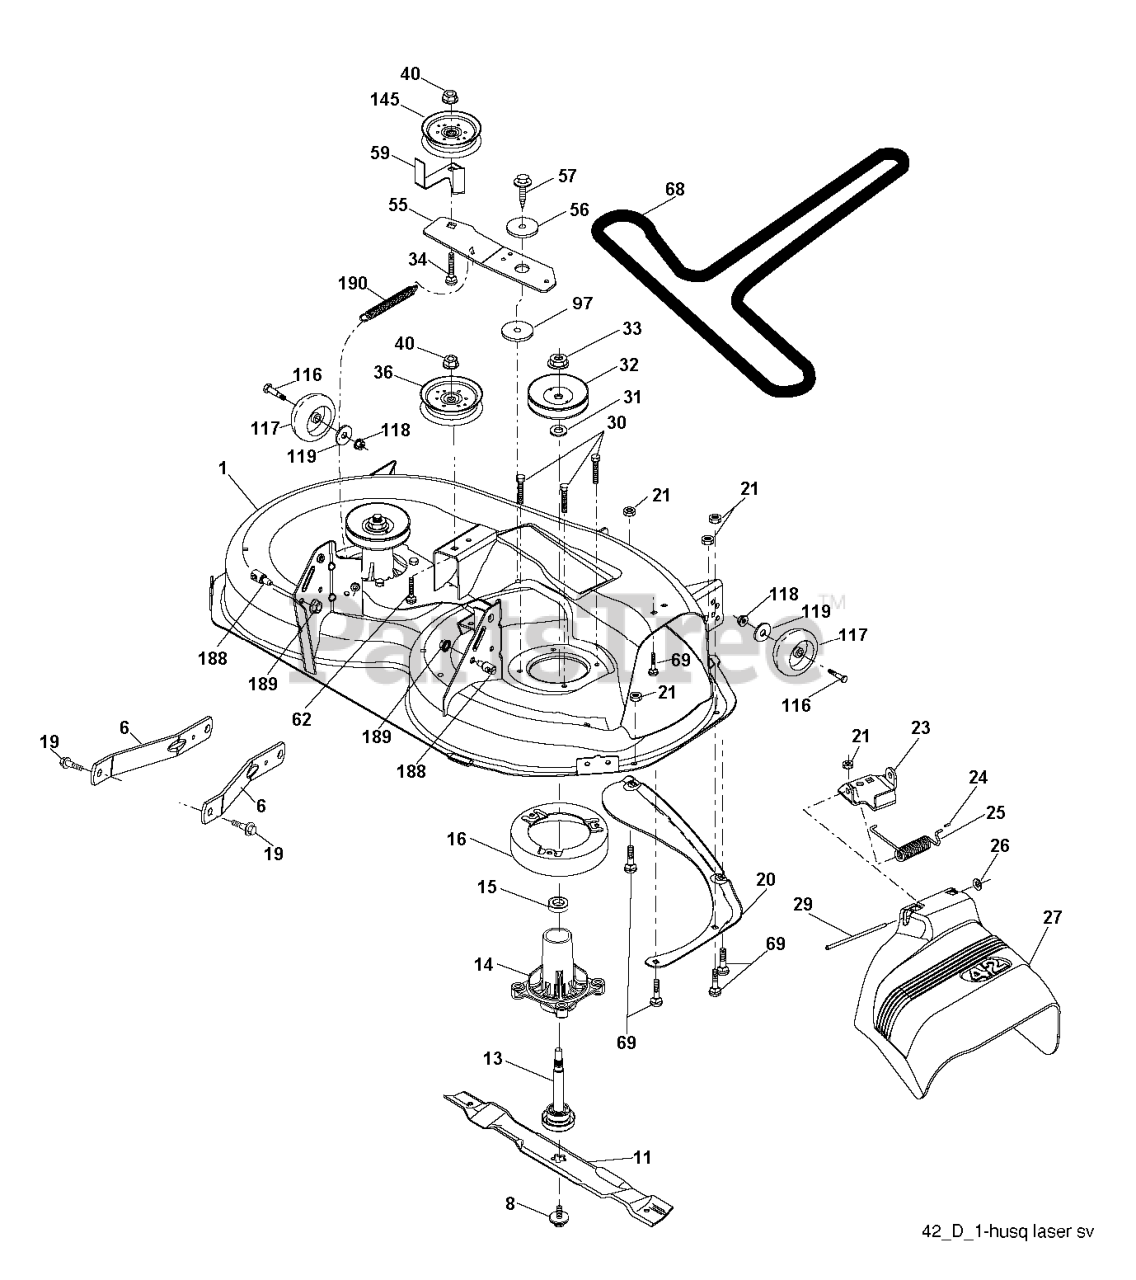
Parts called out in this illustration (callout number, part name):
1	DECK.WELDMENT.42"
6	ARM.SUSPENSION.MOWER.R
8	BOLT.WASHER.ASM.7/16-2
11	42" HI-LIFT BLADE
13	SHAFT.ASM.MDRL.N/GREASE.38
14	RP.HOUSING.MANDREL.4PT.
16	STRIPPER.MANDREL.ROUND.BLACK
19	BOLT.SHOULDER
20	BAFFLE.VORTEX
21	LOCKNUT
23	BRKT.DEFLECTOR.38"2005+
24	CAP-SLEEVE LT
25	SPRING.TORSION.DEFLECT
26	NUT PUSH M
27	SHIELD.DEFLECTOR.MOWER.42"BLAC
29	ROD.HINGE
30	SCREW, WASHER HEAD
31	WASHER.SPACER.MANDREL
32	PULLEY/MANDREL
33	NUT.FLANGE.LOCK.TOP
34	BOLT.3/8-16X1.50
36	PULLEY.IDLER.2006
40	NUT LOCK FLG 3/8-16 UNC
56	SPACER.RETAINER
57	SCREW 3/8-16X1
59	GUARD, BELT
62	BOLT.3/8-16X1.50
68	BELT V SECONDARY
69	BOLT
116	BOLT M
117	WHEEL.GAGE.HALF.SPOKED
118	LOCKNUT
119	WASHER.5/16.FLAT.STE.STD.
145	PULLEY.IDLER.48"PRIMARY
188	STUD.FASTNER.W/ANTI-ROTATE
189	NUT LOCK HEX FLANGE 5/16-18
190	SPRING.MOWER.DRIVE.ELECTRIC
